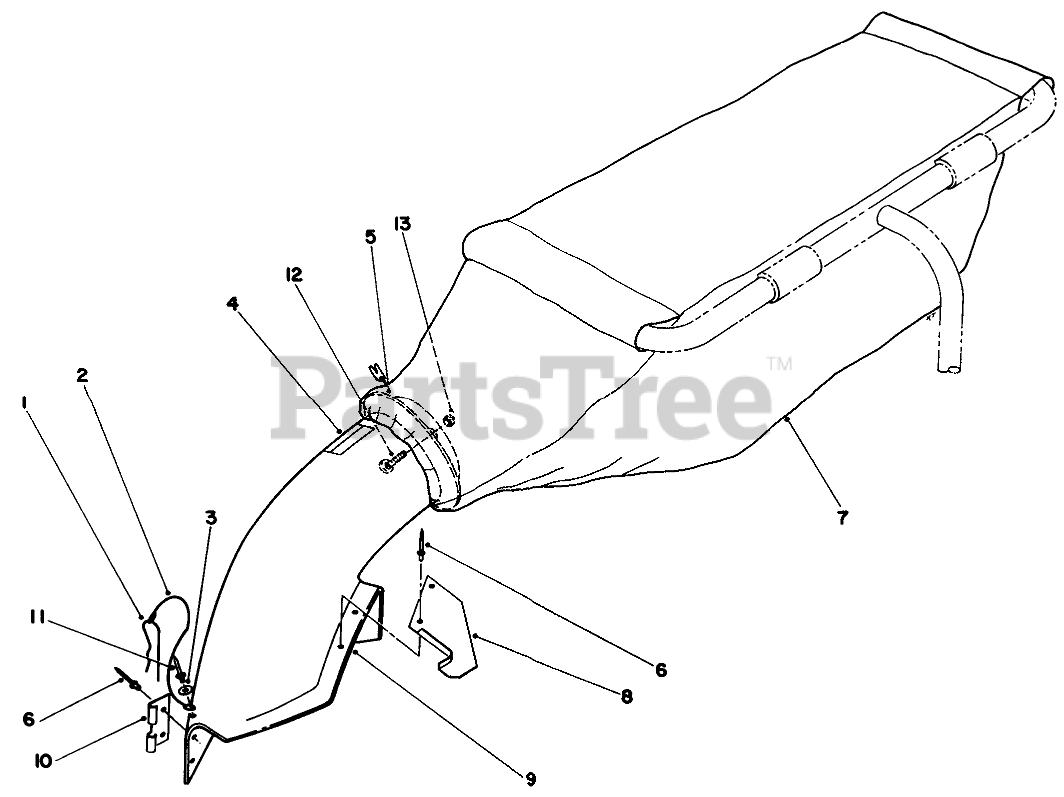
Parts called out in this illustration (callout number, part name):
1	PIN-LOCKING, CHUTE
2	LANYARD
3	WASHER-PLAIN
4	DECAL-DANGER
5	Ring-Bagger
6	RIVET-BLIND
7	BAG ASSEMBLY
8	CHUTE SUPT BRKT
9	Chute Assembly (Incl. Ref. #1-6, 8, 10, & 11)
10	BRACKET-MOUNTING, CHUTE
11	RIVET-BLIND
12	SCREW-CARRIAGE
13	NUT-LOCK, NI
